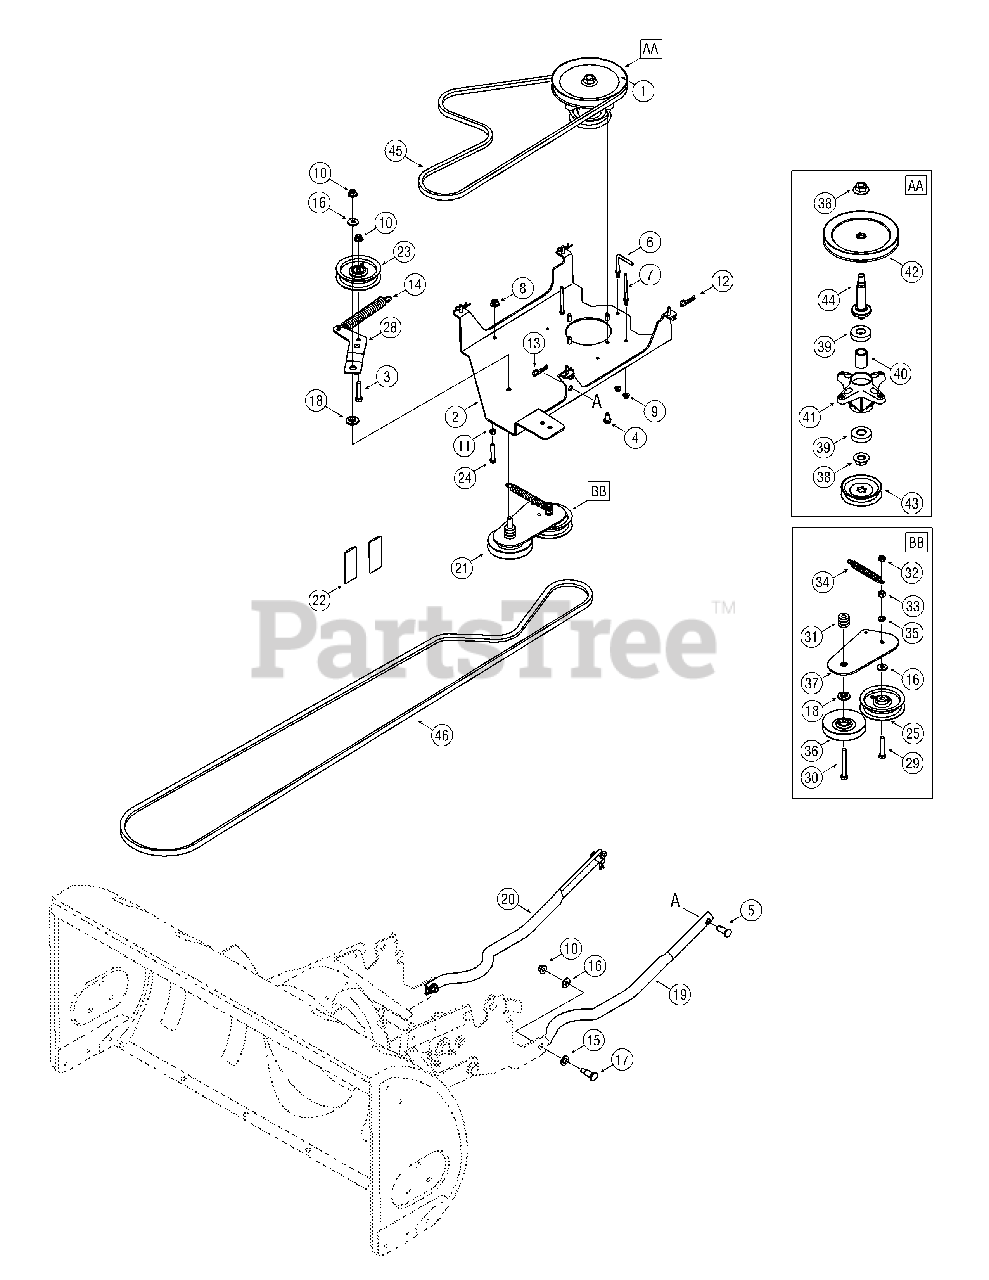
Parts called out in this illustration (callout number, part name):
1	Spindle Assembly (Incl. 38-44)
2	Pulley Mounting Bracket
3	Hex Cap Screw, 3/8-16 x 1.75
4	Self Tapping Screw
5	Clevis Pin, .5 x 1.18
6	Belt Keeper Pin
7	Belt Keeper Pin
8	Nylon Hex Lock Nut, 5/16-18
9	Nylon Hex Lock Nut, 1/4-20
10	Hex Flange Lock Nut, 3/8-16
11	Hex Nut, 5/16-18
12	Click Pin, .092 x 1.64
13	Internal Cotter Pin, .125 x 1.75
14	Extension Spring .91 x 7.33
15	Flat Washer, .531 x .93 x .09
16	Flat Washer, .38 x .93 x .11
17	Shoulder Screw, 3/8-16
18	Shoulder Spacer, .625 x .169
19	LH Support Tube
20	RH Support Tube
21	Double Idler Bracket Assembly
22	Reflector
23	Idler Pulley, 3.50 OD
24	Hex Cap Screw, 5/16-18 x 1.75
25	Idler Pulley 3.50 dia.
28	Idler Bracket
29	Hex Cap Screw, 3/8-24 x 2
30	Hex Cap Screw, 3/8-16 x 3
31	Spacer
32	Nylon Jam Lock Nut, 3/8-24
33	Hex Nut, 3/8-24
34	Extension Spring, .620 x 5.62
35	Lock Washer, 3/8
36	Idler pulley, 4" Diameter
37	Idler Pivot Arm
38	Flange Nut 5/8-18
39	Ball Bearing
40	Spacer
41	Deck Spindle Housing
42	Deck Pulley 7"
43	Pulley 3.75"
44	Spindle Shaft
45	V-Belt
46	V-Belt
